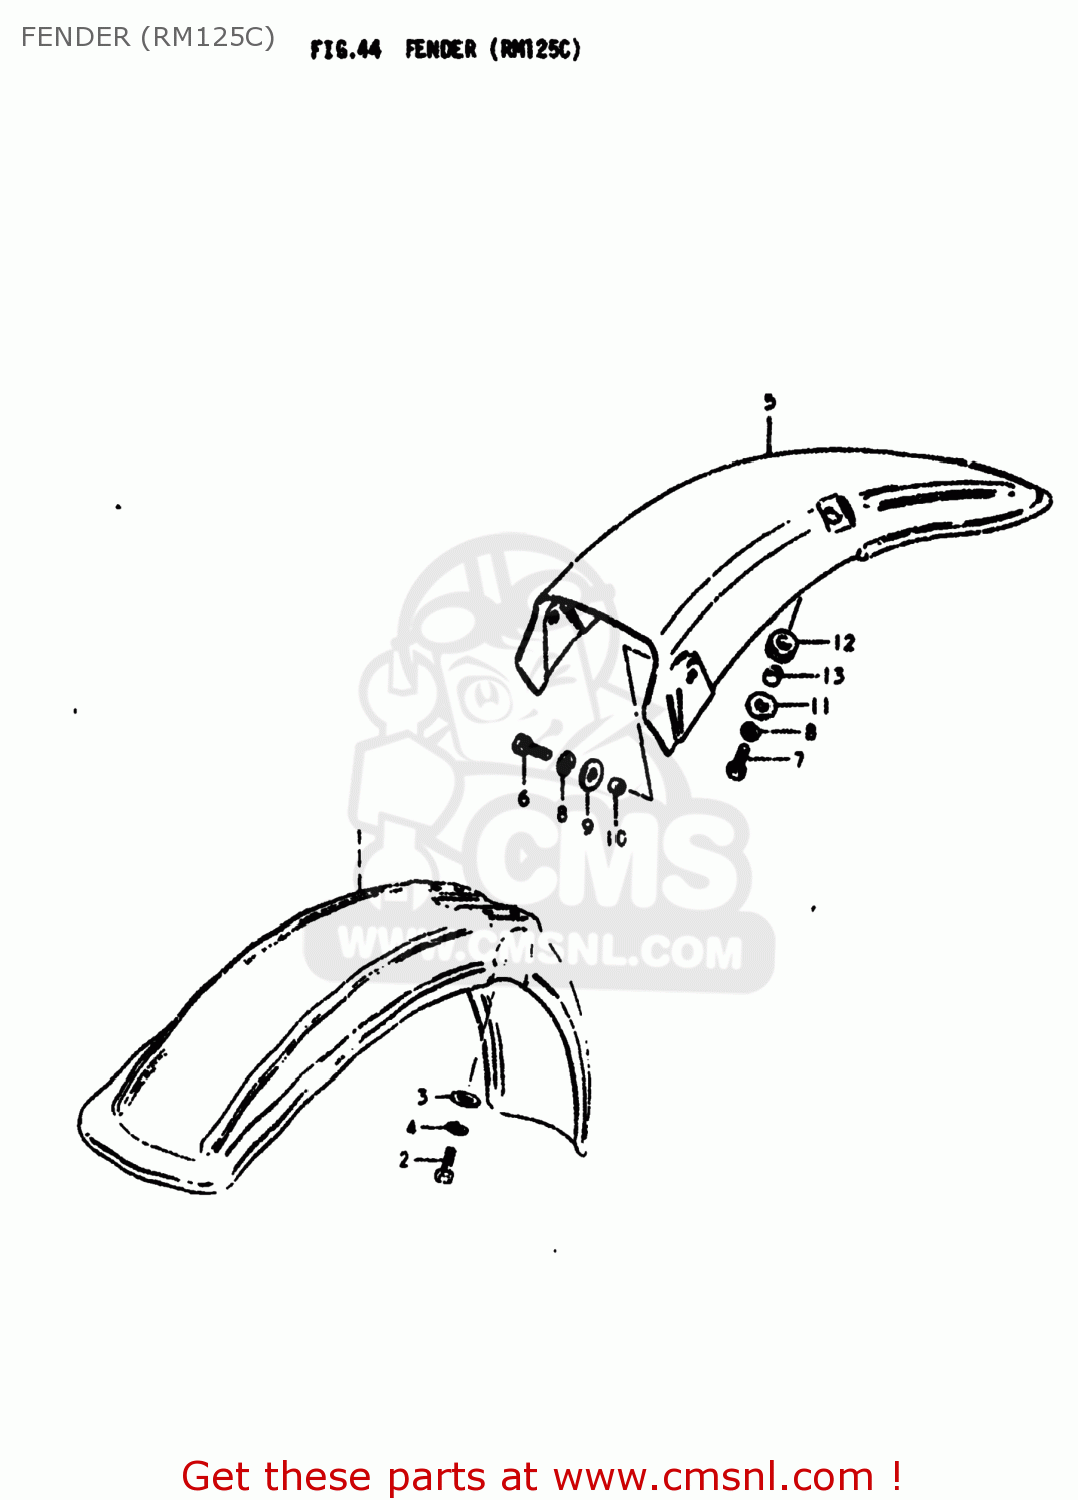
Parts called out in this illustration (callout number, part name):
1	FENDER,FRONT
2	BOLT, UPPER
3	WASHER
4	LOCK WASHER
5	FENDER,REAR
6	BOLT, UPPER
7	BOLT
8	LOCK WASHER
9	WASHER
10	SPACER (6.1X8X5.2)
11	WASHER (6.5X24X1.6)
12	CUSHION
13	SPACER
